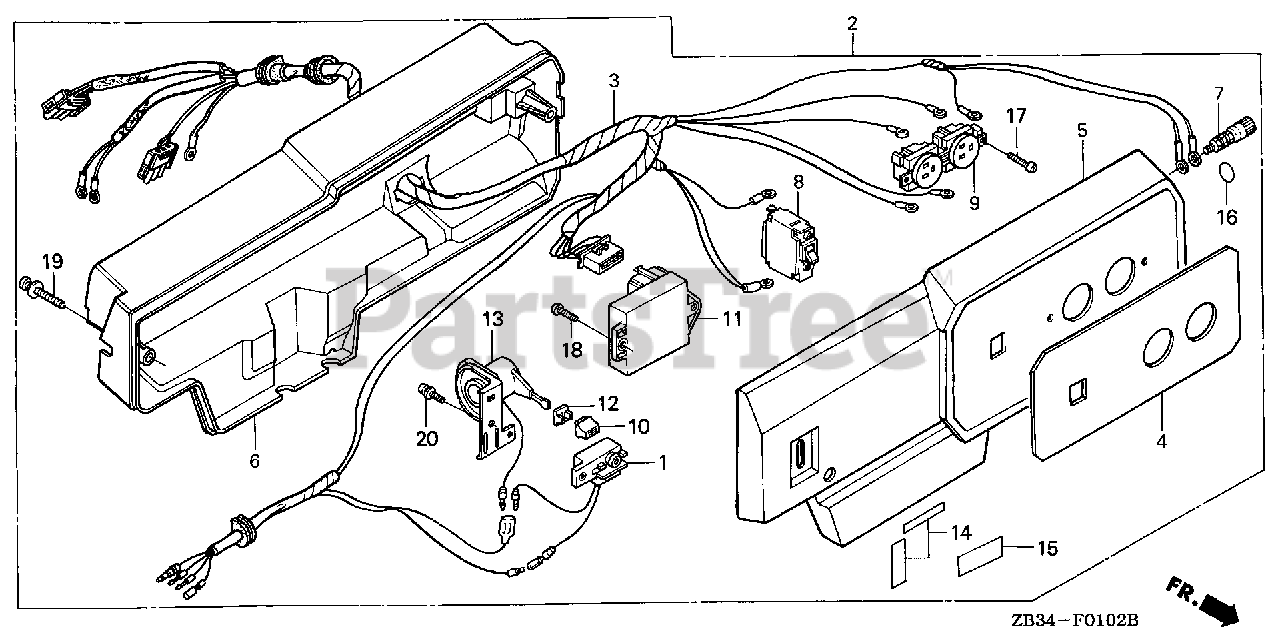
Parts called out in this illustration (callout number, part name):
1	ALERT UNIT, OIL (NOT AVAILABLE)
2	BOX ASSY., CONTROL *R8* (BRIGHT RED)
3	WIRE HARNESS ASSY. (NOT AVAILABLE)
4	MARK, SWITCH PANEL
5	PANEL, CONTROL *R8* (BRIGHT RED)
6	CASE, CONTROL *R8* (BRIGHT RED)
6	CASE, CONTROL *R280* (POWER RED)
7	TERMINAL ASSY., GROUND
8	BREAKER, CIRCUIT (17.5A) (NOT AVAILABLE)
9	RECEPTACLE (15A/125V)
10	KNOB, PETCOCK LEVER
11	REGULATOR UNIT, AUTOMATIC VOLTAGE
12	BUSH, CONTROL KNOB
13	SWITCH ASSY., ENGINE
14	MARK, SWITCH (NOT AVAILABLE)
15	MARK, OIL ALERT (NOT AVAILABLE)
16	MARK, GROUND
17	SCREW, PAN (4X6)
18	SCREW, PAN (5X8)
19	SCREW-WASHER (6X45)
20	SCREW-WASHER (4X8)
